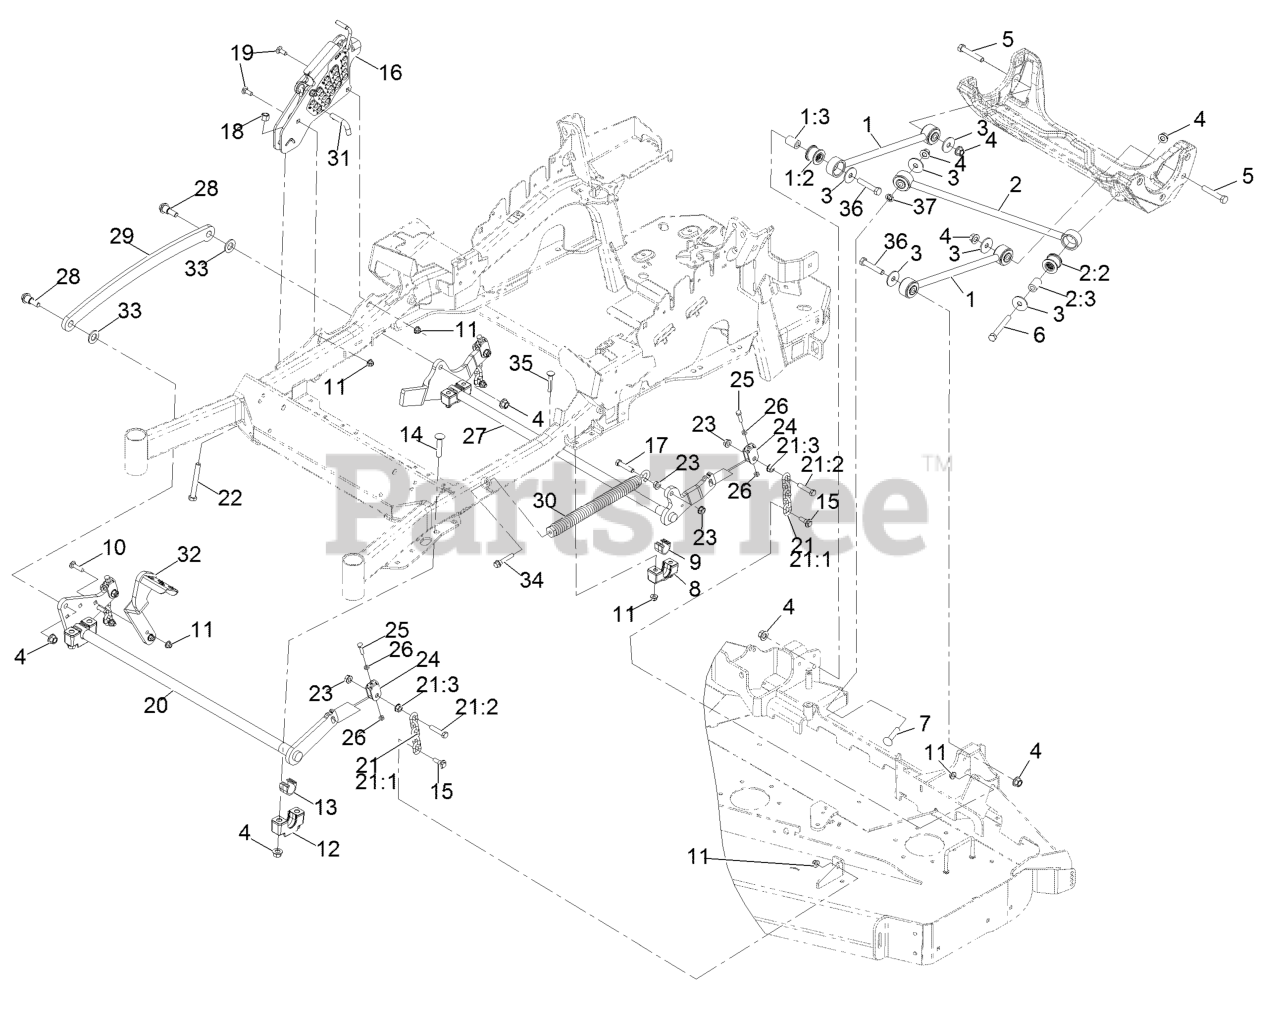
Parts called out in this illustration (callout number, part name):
1	Deck Strut ASM
1:2	Bushing-Suspension, Rubber
2	Panhard Rod ASM
2:2	Bushing-Suspension, Rubber
4	Nut-Lock 1/2-13
5	Screw-HH 1/2-13 X 3
6	Screw-HH 1/2-13 X 4
7	Bolt-Carriage 1/2-13 X 2 1/2
8	Support-Cross Shaft, Bearing Rear
9	Bearing-Cross Shaft, Rear
10	Bolt-Carriage 3/8-16 X 1 1/2
11	Nut-Nyloc 3/8-16 Flg
12	Support-Cross Shaft, Bearing
13	Bearing-Cross Shaft, Front
14	Bolt-Carriage 1/2-13 X 2 1/2 Spl Neck
15	Screw-Hex Flange 3/8-16 X .80
16	HOC ASM
17	Screw-HH 7/16-14 X 2
18	Nut-Nyloc 1/2-13
19	Bolt-Carriage 3/8-16 X 1
20	Decklift-Front
21	Deck Lift Chain ASM
21:1	Chain-Lift, Deck
21:2	Screw-HH 7/16-14 X 2
21:3	Nut-Whizlock 7/16-14
22	Bolt-HH 1/2-13 X 4 Tap
23	Nut-Whizlock 7/16-14
24	Yoke-Adjust, Deck
25	Screw-HH 5/16-18 X 1 1/4
26	Nut-Jam 5/16-18
27	Lift-Deck, Rear
28	Screw-Shoulder HHF 1/2-13 X 1.12
29	Link-Lift, Deck
30	Spring-Extension
31	Pin-HOC
32	Lever-Foot
33	Washer-3/4 Sae
34	Screw-Shcs 3/8-16 X 2.212
35	Bolt-Carriage 3/8-16 X 2 1/4
36	Screw-HH 1/2-13 X 2 3/4
37	Nut-Push
